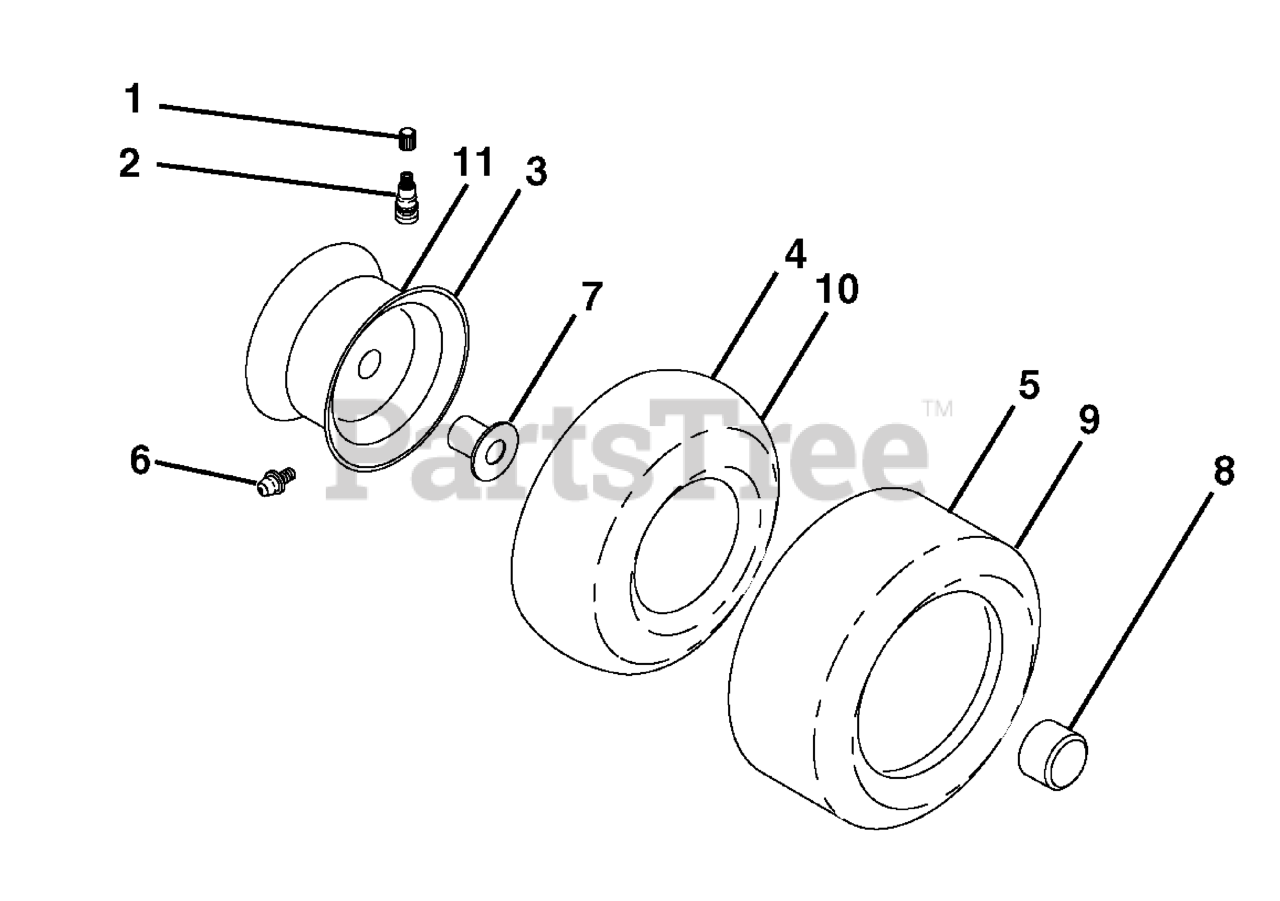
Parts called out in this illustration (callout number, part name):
1	Cap, Valve, Tire
2	Stem, Valve
3	Rim Assembly, Front
4	Tube, Front
5	Tire, Front
6	Fitting, Grease
7	Bearing, Flange
8	Cap, Axle (Front Wheel Only)
9	Tire, Rear
10	Tube, Rear
11	Rim Assembly, Rear
